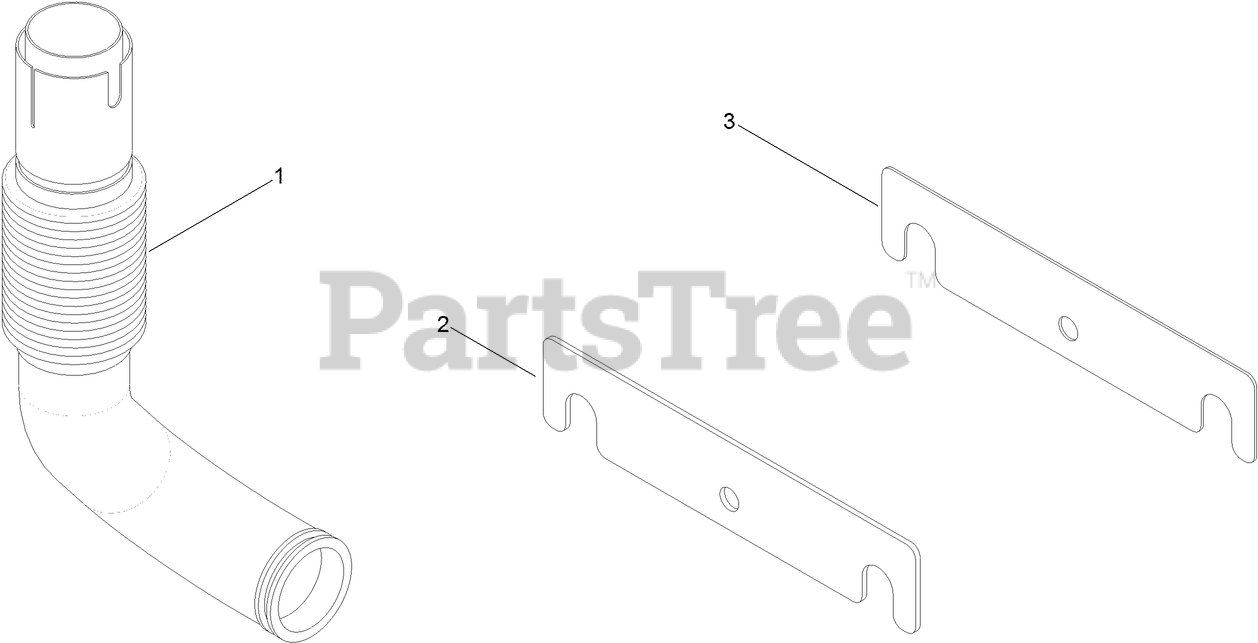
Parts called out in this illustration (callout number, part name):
1	TURBO PIPE ASM
2	PLATE-SHIM
3	PLATE-SHIM
